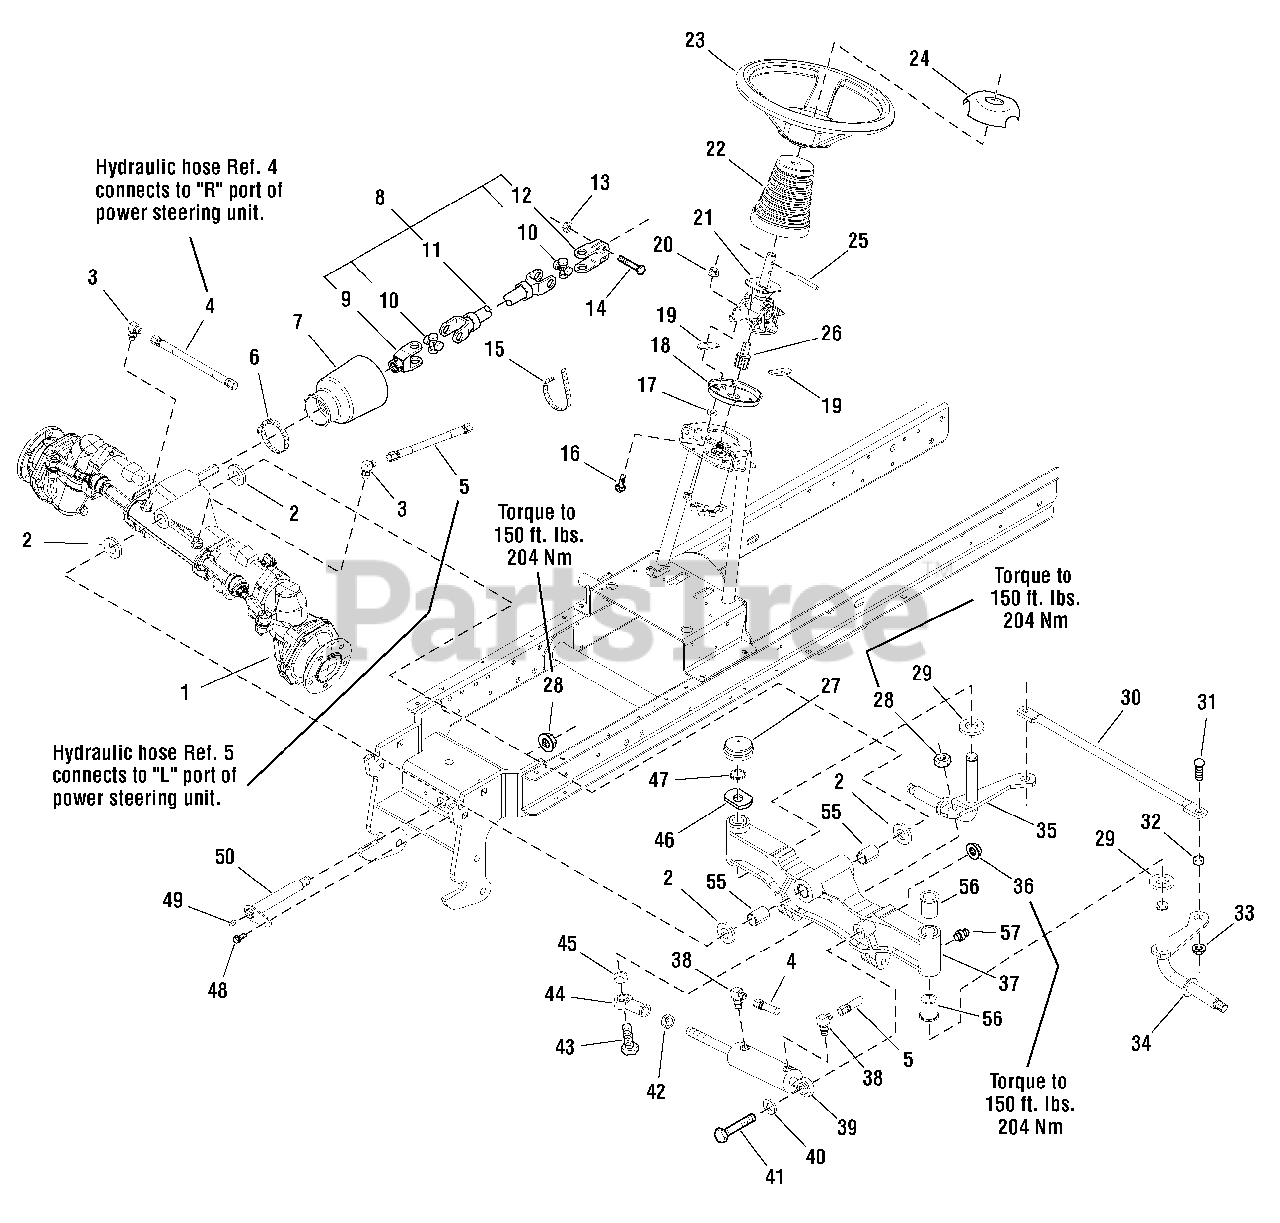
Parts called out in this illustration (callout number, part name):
1	AXLE ASSSEMBLY
2	WASHER (Mfg. Nos. 1690846 & 1690912 Only)
3	FITTING, Elbow Hose
4	HOSE ASSEMBLY, Hydraulics, R.H.
5	HOSE ASSEMBLY, Hydraulics, L.H.
6	CLAMP, Worm Hose
7	COVER, Drive Shaft
8	SHAFT ASSEMBLY
9	YOKE & FLANGE, Drive Shaft
10	CROSS & BEARING KIT, Includes Grease Fitting
11	YOKE & TUBE ASSEMBLY
12	YOKE, Drive Shaft
13	NUT, Hex Lock, ESNA LIGHT, 3/8-16
14	BOLT, 3/8-16 X 1-3/4, GR 5, CZ
15	TIE, Self Locking, 15" Long
16	BOLT, Carriage, Short Neck, 5/16-18 x 1-1/4, G5
17	NUT, Push Pal, 5/16 DIA Thread, 5/8 OD
18	PLATE, Steering
19	SPACER, Tilt Steering
20	NUT, Hex, 5/16-18
21	TILT STEERING UNIT, Straight Shaft
21	TILT STEERING UNIT, Legacy
22	BELLOWS, Tilt Steering Unit With Slot
23	STEERING WHEEL
24	CAP, Steering Wheel
25	PIN, Spring, 5/16 x 2-1/2, Black
26	ADAPTER TILT, 9 Tooth With Powerdered Metal
27	COVER, Spindle
28	NUT, Hex, Toplock Flange 3/4-10
29	WASHER, 1 x 2-1/4 x 1/8
31	BOLT, Carriage, 7/16-14 x 1-1/4
32	SPACER, .390 LG With Powdered Metal
33	NUT, Hex, Toplock Flange, 7/16-14
34	SPINDLE & ARM ASSEMBLY, Left Hand
35	SPINDLE & ARM ASSEMBLY, Right Hand
36	NUT, Hex, Toplock M16-2.00 BLACK
37	AXLE & BUSHINGS ASSEMBLY
38	FITTING, Elbow Hose
39	CYLINDER, Hydraulic Steering
40	WASHER, 5/8
41	CAPSCREW, Hex Head, M16-2.00 X 110MM, 8.8 BLK
42	NUT, Hex, Jam, 3/4-16
43	CAPSCREW, Hex Head, 3/4-10 x 2-1/2 G5
44	BALL JOINT ASSEMBLY
45	SPACER, 3/4 x 1-1/16 x 3/8, Powder Metal
47	RING, Retainer
48	SCREW, Taptite, 5/16-18 x 3/4
49	FITTING, Lube, 1/4
50	SHAFT & ANCHOR ASSEMBLY, Pivot
51	NUT, Hex Lock, ESNA Light, 5/8-18, Thin
52	SPACER, Grass Shield, 0.793 x 1-3/4 x 1/4
53	CUP, Spindle. 0.793HOLE E-COAT
54	O-RING 0.739 ID .070 WIDTH SAE-TYPE 1
55	BUSHING-1.004IDX1.250ODX1.075 LG 1045CRS
56	BUSHING-0.987IDX1.251ODX1.50 LG PM
57	FITTING, Lube, 1/4
